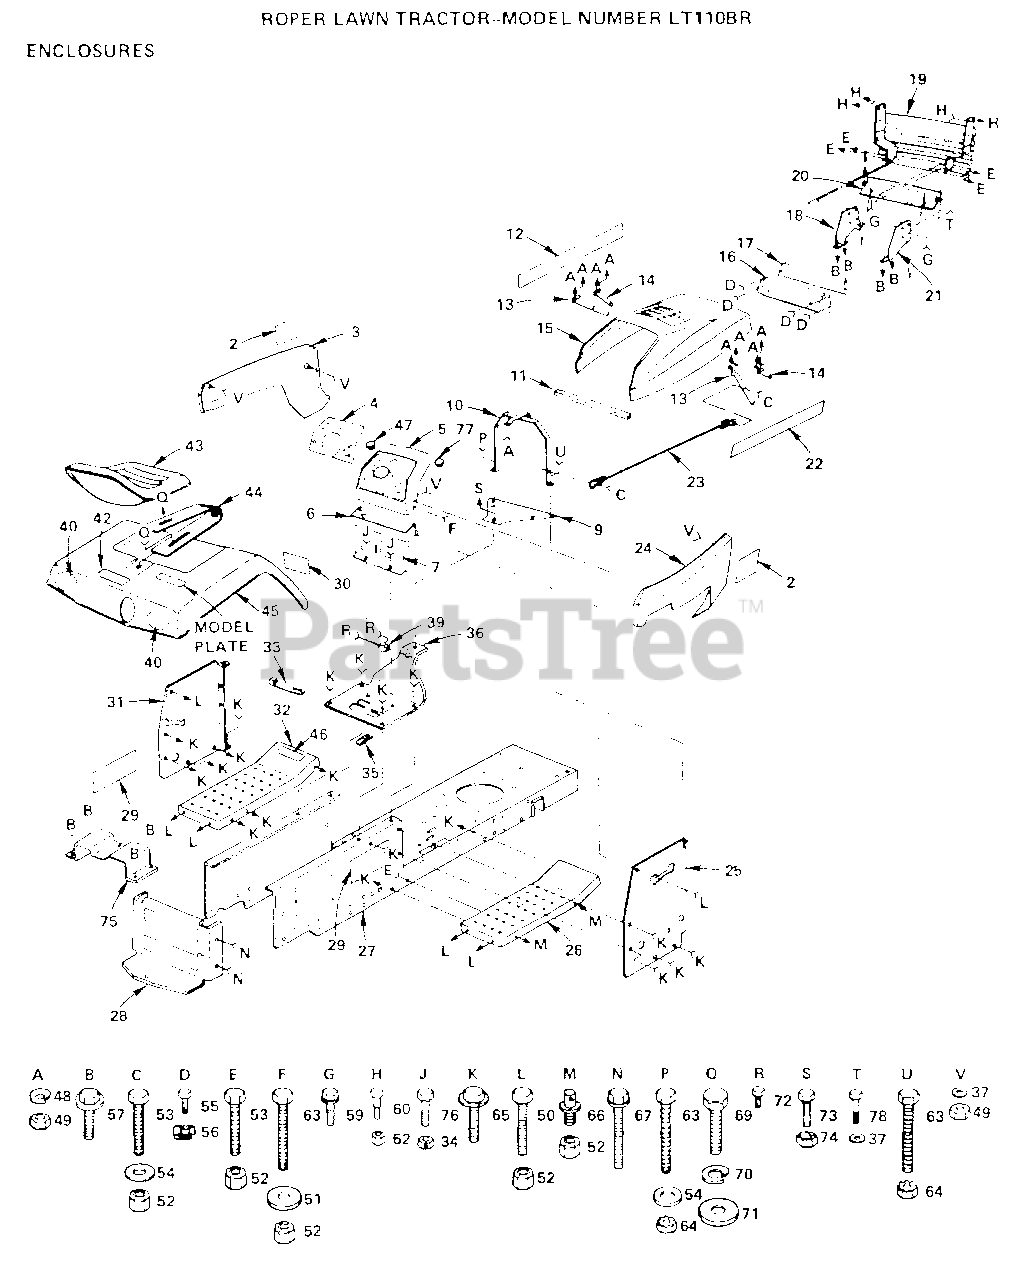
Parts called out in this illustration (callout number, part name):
6	DASH ASSY LT
7	DECAL, INSTRUCTION
9	PLATE, SUPPORT BATTERY
10	SUPPORT ASSY LT
11	FOAM-STRIP LT
18	SUPPORT-GRILL LT
30	DECAL-CAUTION
33	WIRE TIE
35	CLIP T
37	WASHER PM
47	PLUG-DASH T
51	WASHER
53	BOLT
54	WASHER
56	"""J"" FASTENER LT"
57	SCREW
59	SCREW
60	BOLT T
64	NUT
65	SCREW LT
66	PIN SUSPENS. LTV
67	SCREW GTV
69	BOLT
71	WASHER
73	BOLT
77	PLUG BUTTON T
78	SCREW HEX CRT
